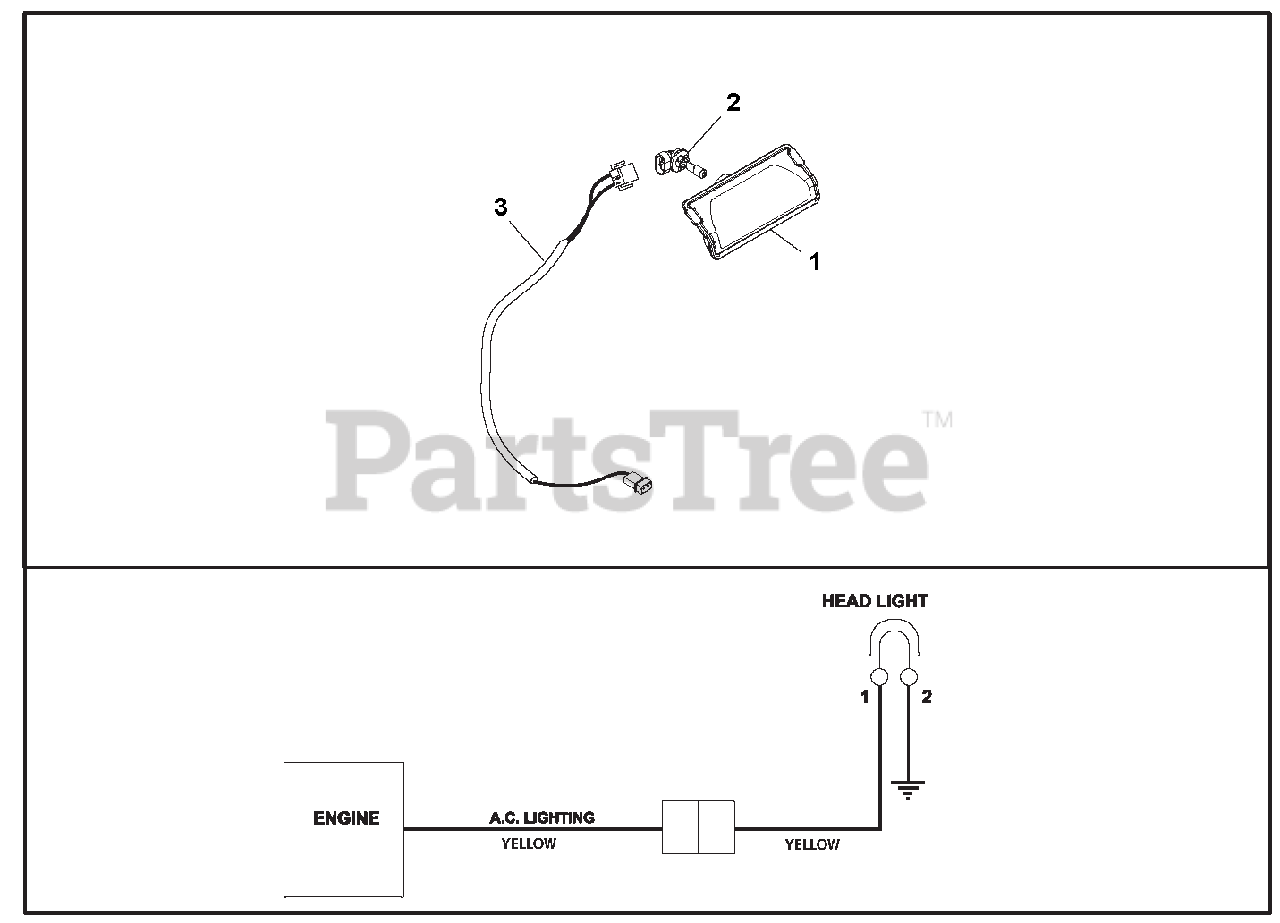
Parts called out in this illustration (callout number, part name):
1	HEADLIGHT ASY, HALO 20W 2SHOT
2	BULB, LIGHT-HALOGEN 20W
3	HARNESS, LIGHT - COMPACT
